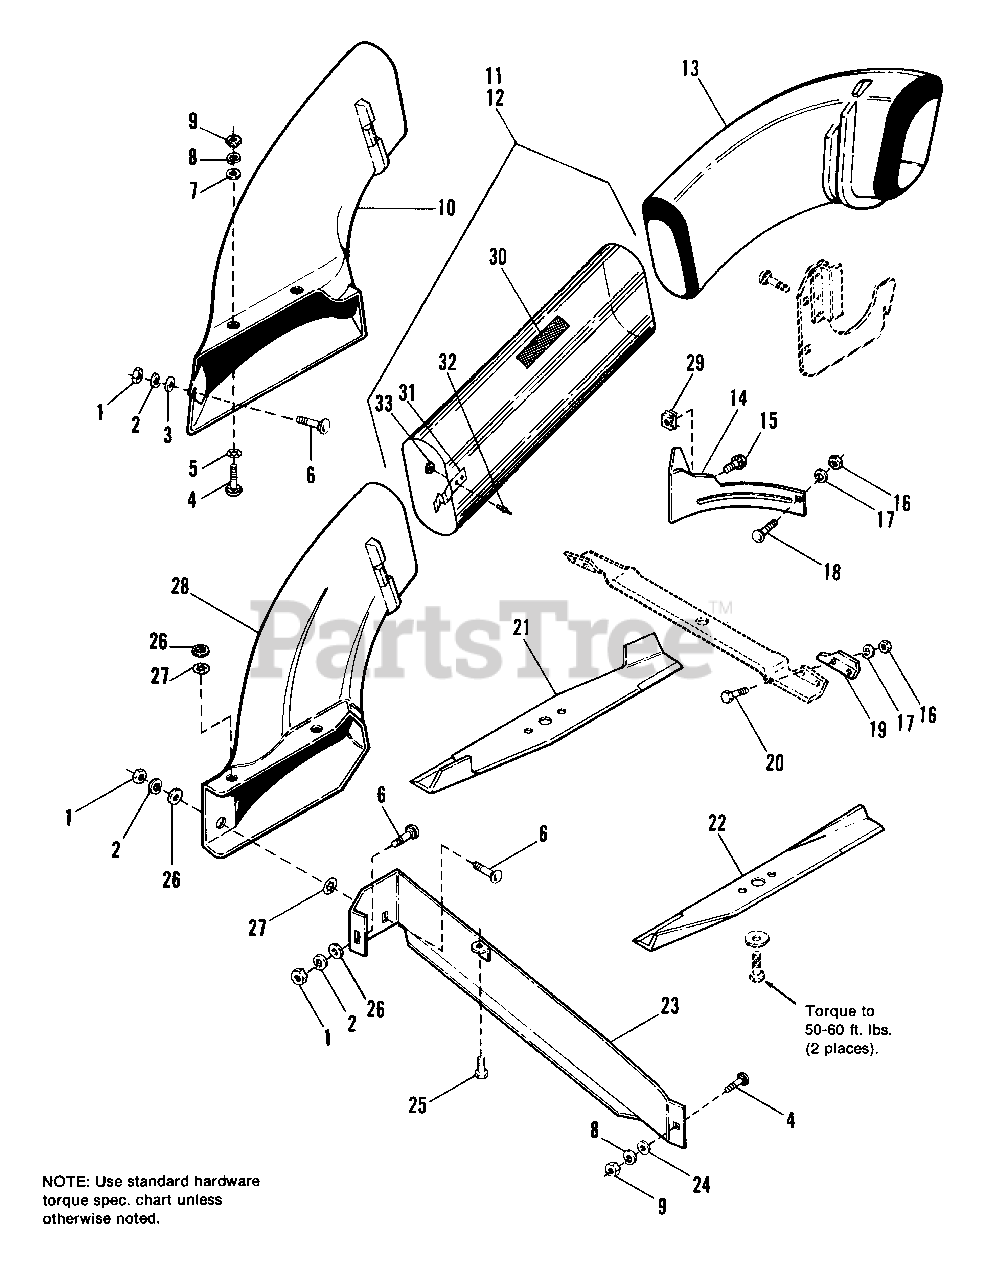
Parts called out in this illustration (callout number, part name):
1	NUT, Hex, 3/8-16 (Qty 1 on 1690822)
2	LOCKWASHER, 3/8 (Qty.1 on 1690822)
3	WASHER, 13/32 x 1 (1690822 Only)
4	BOLT, Carriage, 5/16-18 x 7/8
5	NUT, Push On (1690822 only)
6	BOLT, Carriage, 3/8-16 x 3/4 (Qty.1 on 1690822)
7	WASHER (1690822 only)
8	LOCKWASHER, 5/16 (Qty.1 on 1690820)
9	NUT, Hex, 5/16-18 (Qty.1 on 1690820)
10	ADAPTOR ASSY. (1690822 only)
11	TUBE ASSY. (1690820 only) (Incl. Ref. Nos. 30-33)
12	TUBE ASSY. (1689822 only) (Incl. Ref. Nos. 30-33)
14	BAFFLE, Deflector, Side (1690820 only)
15	SCREW, Whizlock,1/4-20 x 1/2 (1690820 only)
16	NUT, Hex, 1/4-20 (Qty.1 on 1690820)
17	LOCKWASHER, 1/4 (Qty.1 on 1690820)
18	BOLT, Carriage, 1/4-20 x 5/8 (1690820 only)
19	PLATE, Lift (1690822 only)
20	CAPSCREW, 1/4-20 x 5/8 (1690822 only)
21	BLADE, R.H. Side (1690820 only)
22	BLADE, L.H. Side (1690820 only)
23	BAFFLE ASSY., Discharge (1690820 only)
24	LOCKWASHER, 1/4 (1690820 only)
25	SCREW, Taptite, 5/16-18 x 1/2 (1690820 only)
26	WASHER, 3/8 (1690820 only)
27	NUT, Push On (1690820 only)
28	ADAPTOR (1690820 only)
29	NUT, Retainer, 1/4-20 (1690820 only)
30	DECAL, Cleaning Instructions.
31	SPRING, Retaining, Tube
32	RIVET, Tube
33	WASHER, Rivet
